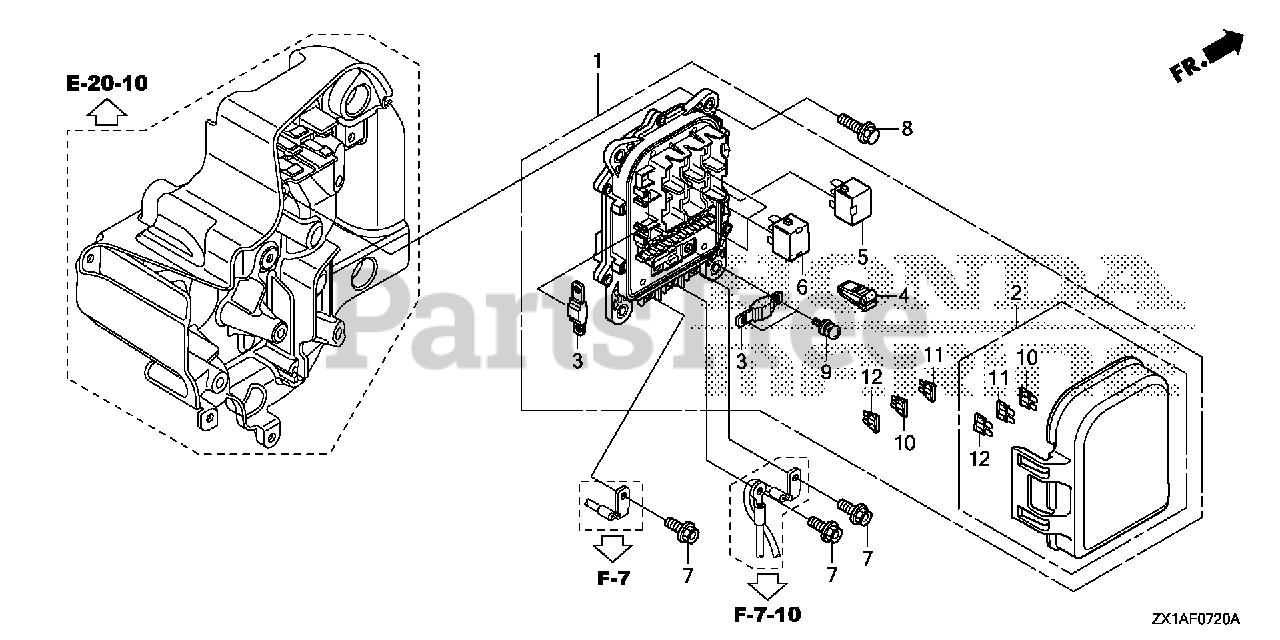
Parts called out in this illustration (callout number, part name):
1	BOX ASSY., JUNCTION
2	COVER, FUSE
3	FUSE, BLOCK (100A) (L-TYPE)
4	PULLER, MINI FUSE
5	RELAY ASSY., FUEL PUMP (DENSO)
6	RELAY ASSY., POWER (12V-20A) (MICRO ISO 4P)
7	BOLT, FLANGE (6X12)
8	BOLT, FLANGE (6X20)
9	SCREW-WASHER (5X15)
10	FUSE, MINI (10A)
11	FUSE, MINI (15A)
12	FUSE, MINI (30A)
